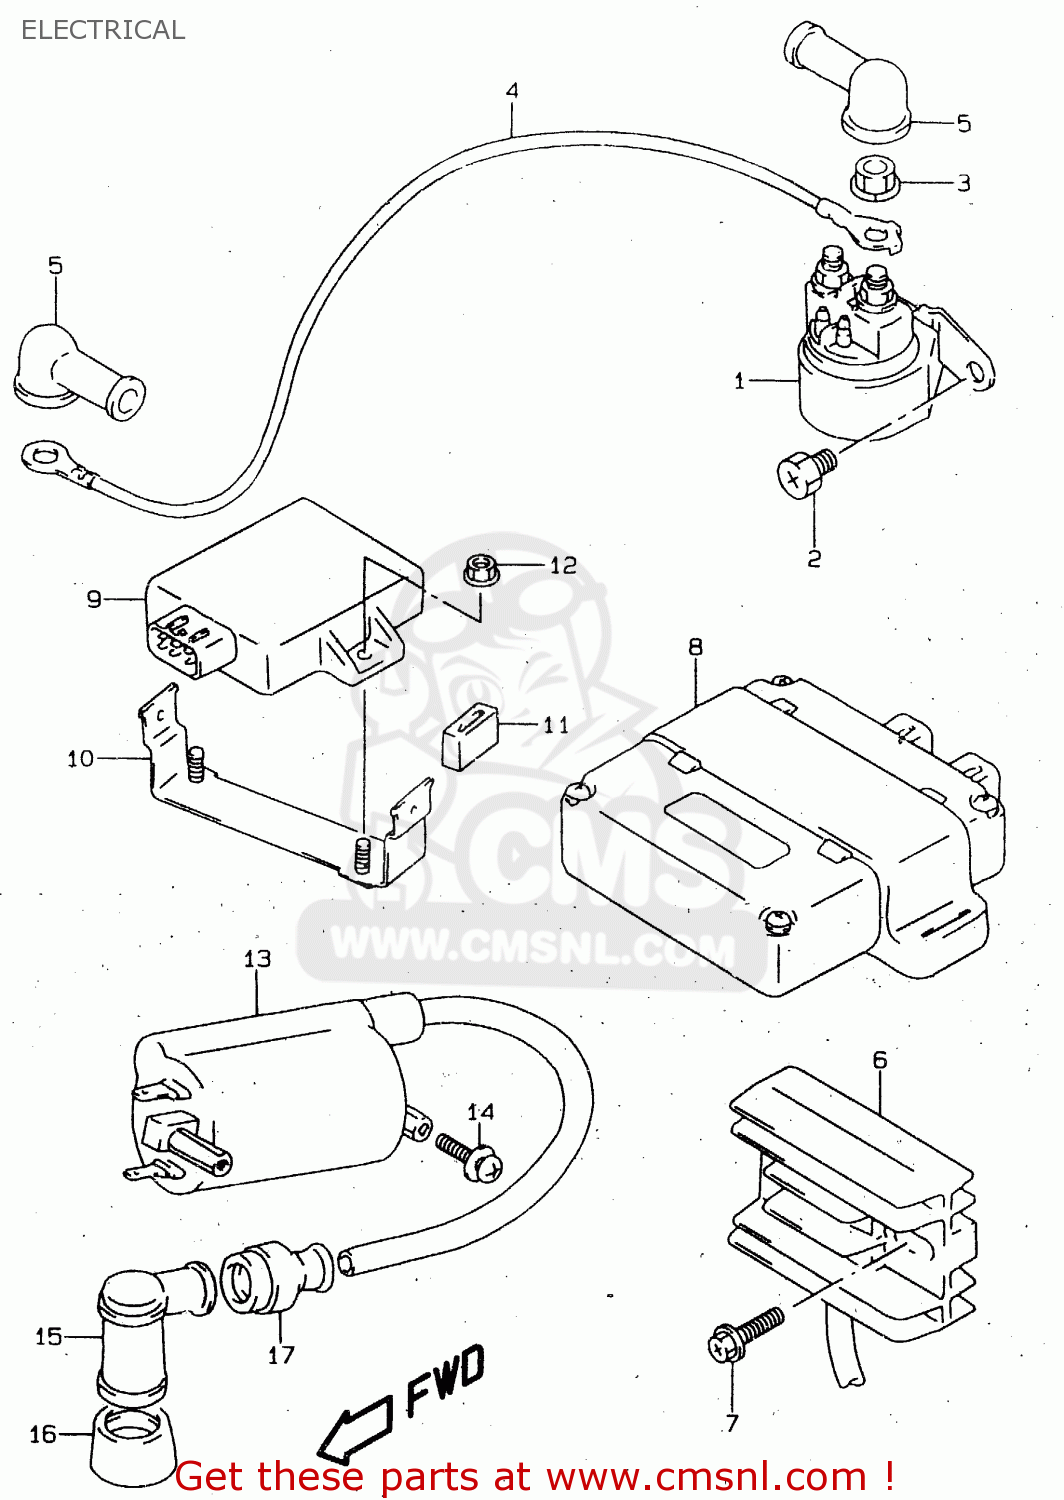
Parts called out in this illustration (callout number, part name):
1	RELAY ASSY,STARTING MOTOR
2	SCREW(6X10)
3	NUT
4	WIRE,STARTER MOTOR
5	CAP,TERMINAL
6	RECTIFIER ASSY
7	BOLT(6X20)
8	IGNITOR UNIT
9	IGNITOR ASSY
10	BRACKET,IGNITOR
11	CUSHION,IGNITOR
12	NUT
13	COIL ASSY,IGNITION
14	SCREW
15	CAP ASSY,SPARK PLUG
16	SEAL,SPARK PLUG CAP
17	SEAL,HIGH TENSION CORD
